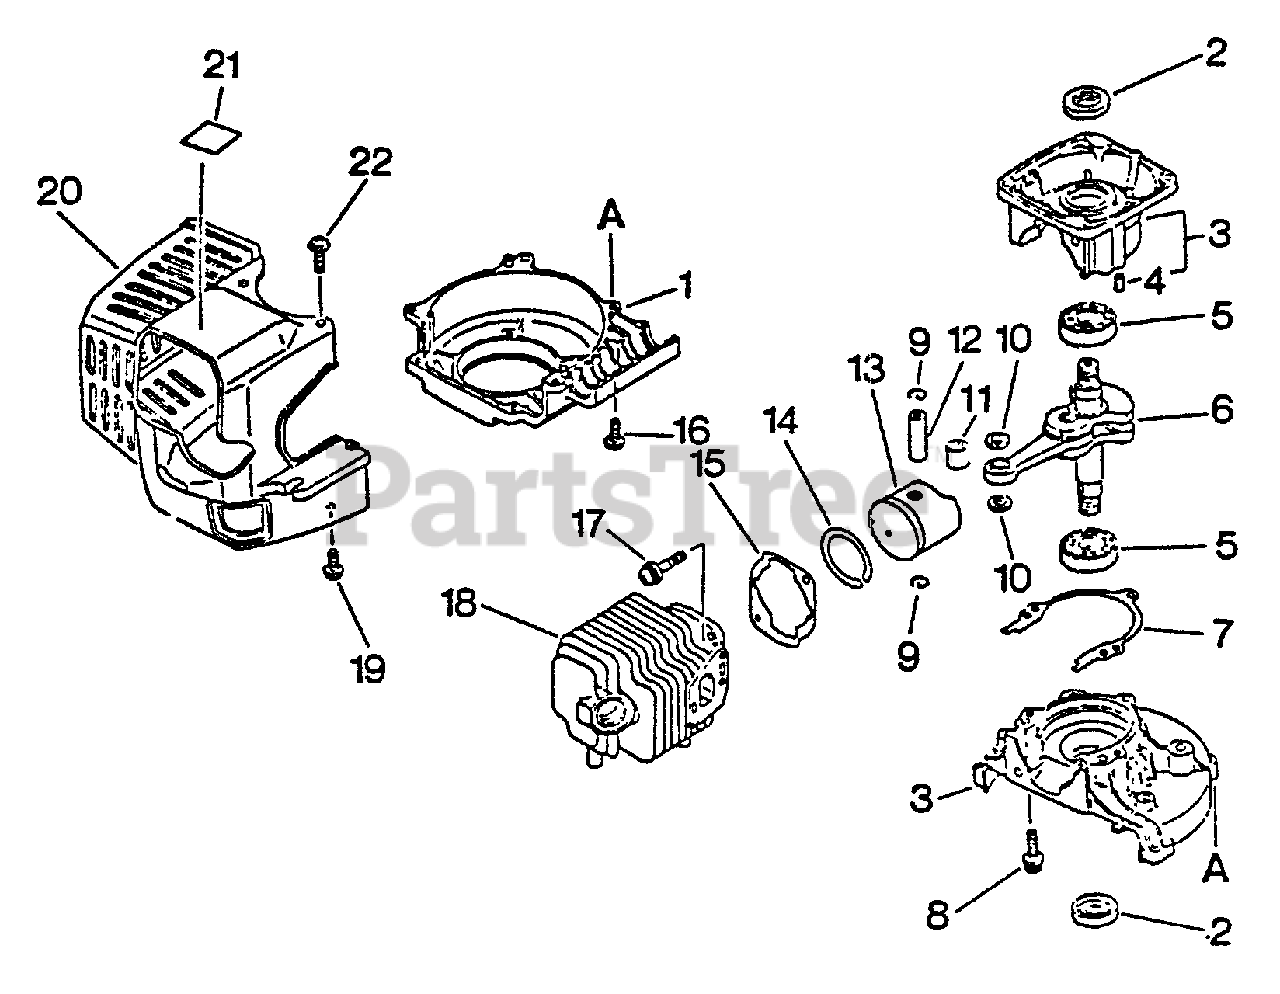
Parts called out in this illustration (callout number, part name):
1	CASE, FAN
2	SEAL, OIL
3	CRANKCASE KIT
4	PIN - LOCATING
5	BEARING, BALL - 6201
6	CRANKSHAFT ASSY
7	GASKET, CRANKCASE
8	SCREW - 5X28
9	RING, RETAINING
10	SPACER, PISTON
11	BEARING, NEEDLE
12	PIN, PISTON
13	PISTON
14	RING, PISTON
15	GASKET, CYLINDER
16	SCREW - 4X14
17	SCREW - 5X22
18	CYLINDER
19	SCREW - 4X16
20	COVER, ENGINE - ORANGE
20	COVER, ENGINE - GRAY
21	LABEL - MODEL
22	SCREW - 4X12
